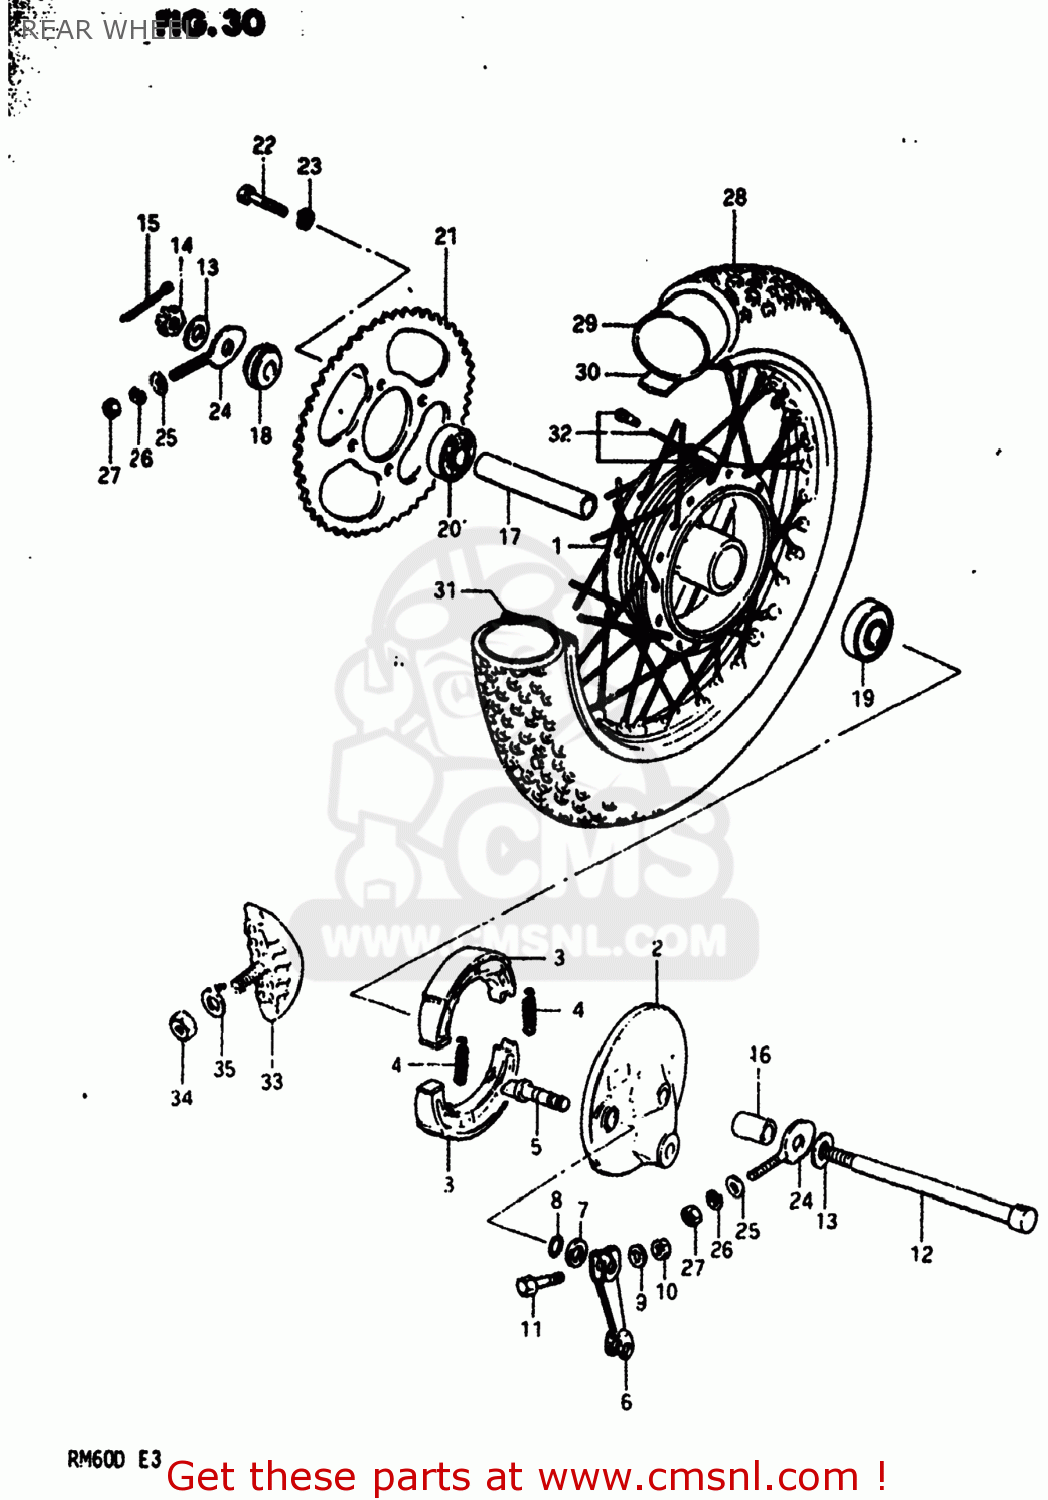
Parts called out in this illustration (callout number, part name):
1	DRUM SET,REAR HUB
2	PANEL,REAR BRAKE ANCHOR
3	SHOE,BRAKE (MCA)
4	SPRING(L:34)
5	CAM,FRONT BRAKE
6	LEVER,REAR BRAKE CAM
7	WASHER (14.5X22X1.6)
8	O-RING (D:2.4 ID:13.8)
9	WASHER
10	NUT
11	BOLT(6X33)
12	AXLE,REAR
13	WASHER
14	NUT 12MM
15	COTTER PIN
16	SPACER (12.1X22X27)
17	SPACER(12.6X19X91)
18	SPACER,RR AXLE,L
19	BEARING
20	BEARING
21	SPROCKET,RR(NT:42)
22	BOLT(10X33)
23	LOCK WASHER
24	ADJUSTER,CHAIN,R
25	WASHER
26	LOCK WASHER
27	NUT
28	TIRE
29	TUBE,INNER
30	PROTECTOR,INNER TUBE
31	RIM,REAR WHEEL
32	SPOKE SET,REAR WHEEL
33	STOPPER,BEAD
34	NUT
35	WASHER
